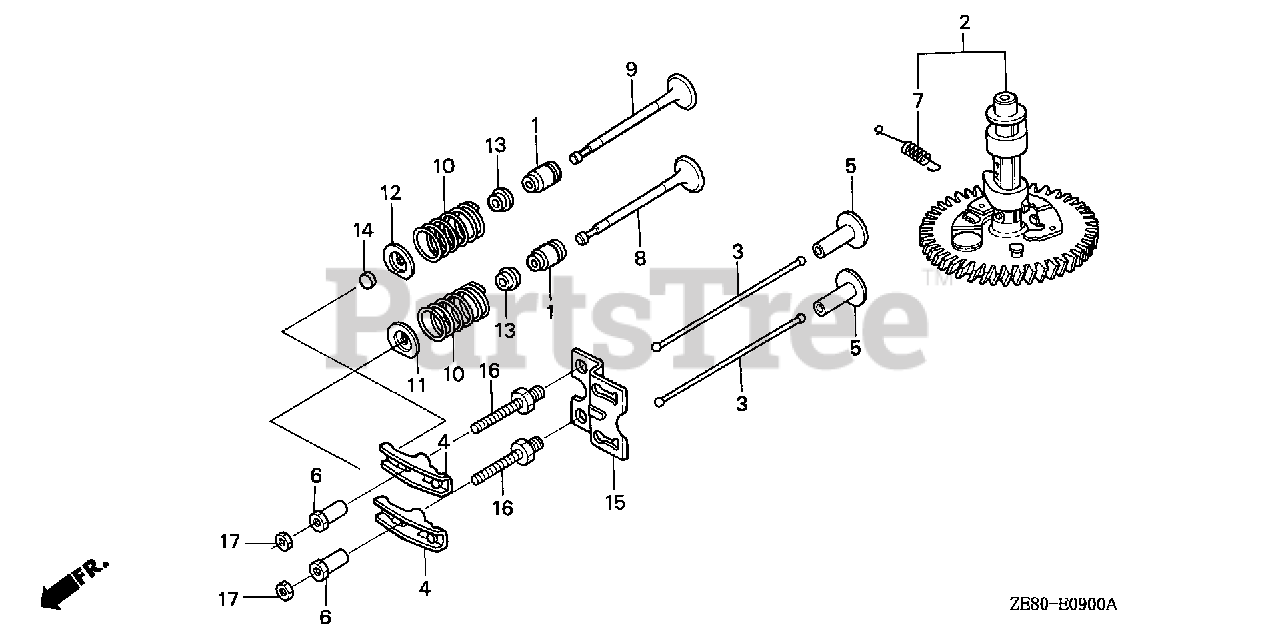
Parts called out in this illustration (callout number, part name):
1	SEAL, VALVE STEM
2	CAMSHAFT ASSY.
2	CAMSHAFT ASSY. (NOT AVAILABLE)
4	ARM, VALVE ROCKER
5	LIFTER, VALVE
6	PIVOT, ROCKER ARM
7	SPRING, WEIGHT RETURN
8	VALVE, IN.
9	VALVE, EX.
10	SPRING, VALVE
11	RETAINER, IN. VALVE SPRING
12	RETAINER, EX. VALVE SPRING
13	SEAT, VALVE SPRING
14	ROTATOR, VALVE
15	GUIDE, PUSH ROD
16	BOLT, PIVOT (8MM)
17	NUT, PIVOT ADJUSTING
